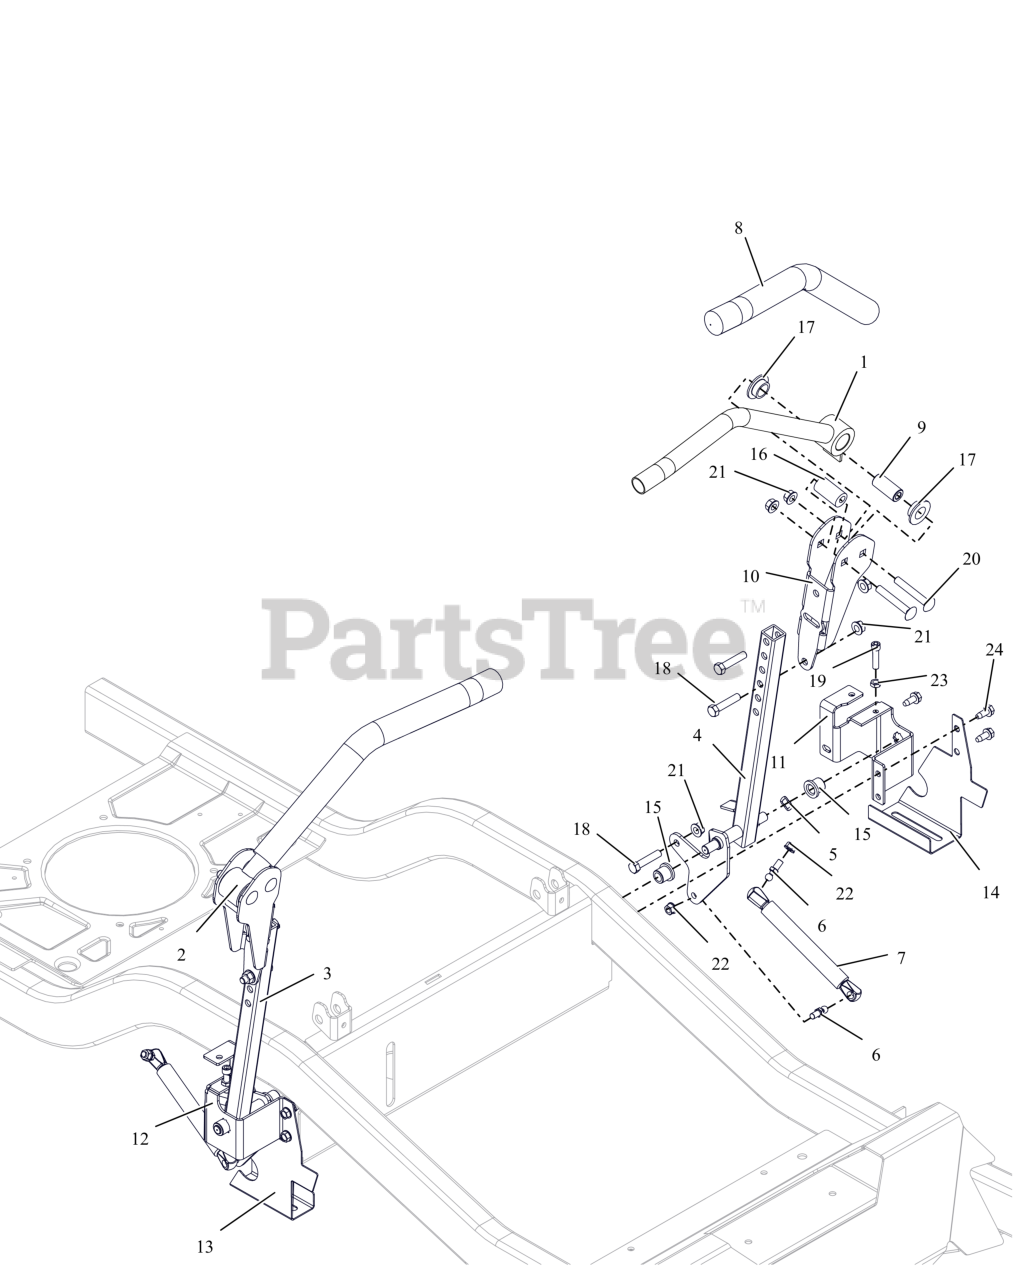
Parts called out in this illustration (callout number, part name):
1	WLDMT, CONTROL HANDLE- BLK
2	WLDMT, CONTROL HANDLE- BLK
3	WLDMT, STEERING RH
4	WLDMT, STEERING LH
5	WAVE WASHER .531X.781X.125FH
6	STUD- BALL
7	DAMPER
8	GRIP, HANDLEBAR
9	SPACER, STEERING ARM
10	ADJ UPPER CONTROL ARM BRKT-BLK
11	BRKT, STEERING ARM MOUNT -LH
12	BRKT, STEERING ARM MOUNT -RH
13	GUARD, FRAME RAIL BELT RH
14	GUARD, FRAME RAIL BELT LH
15	BHSG-FLG .500X.750X.750X.125
16	BSHG, ECCENTRIC.406X.875X1.625
17	BSHG-FLG .762X1.48X.44 NYL
18	BLT, HEX .38-16X1.75 G5 ZCC
19	BLT, SHCS .312-18X1.25 G8 SS
20	BLT, RHSSN.38-16X2.50 G5 ZCC
21	NUT-LK-TOP-FLG .38-16 ZC120
22	NUT,LK-CTR-FLG .31-18 GF ZCC
23	NUT-JAM .312-18 G2 ZCC
24	SCR,TAP .312-18X.75 HWH TR ZCC
